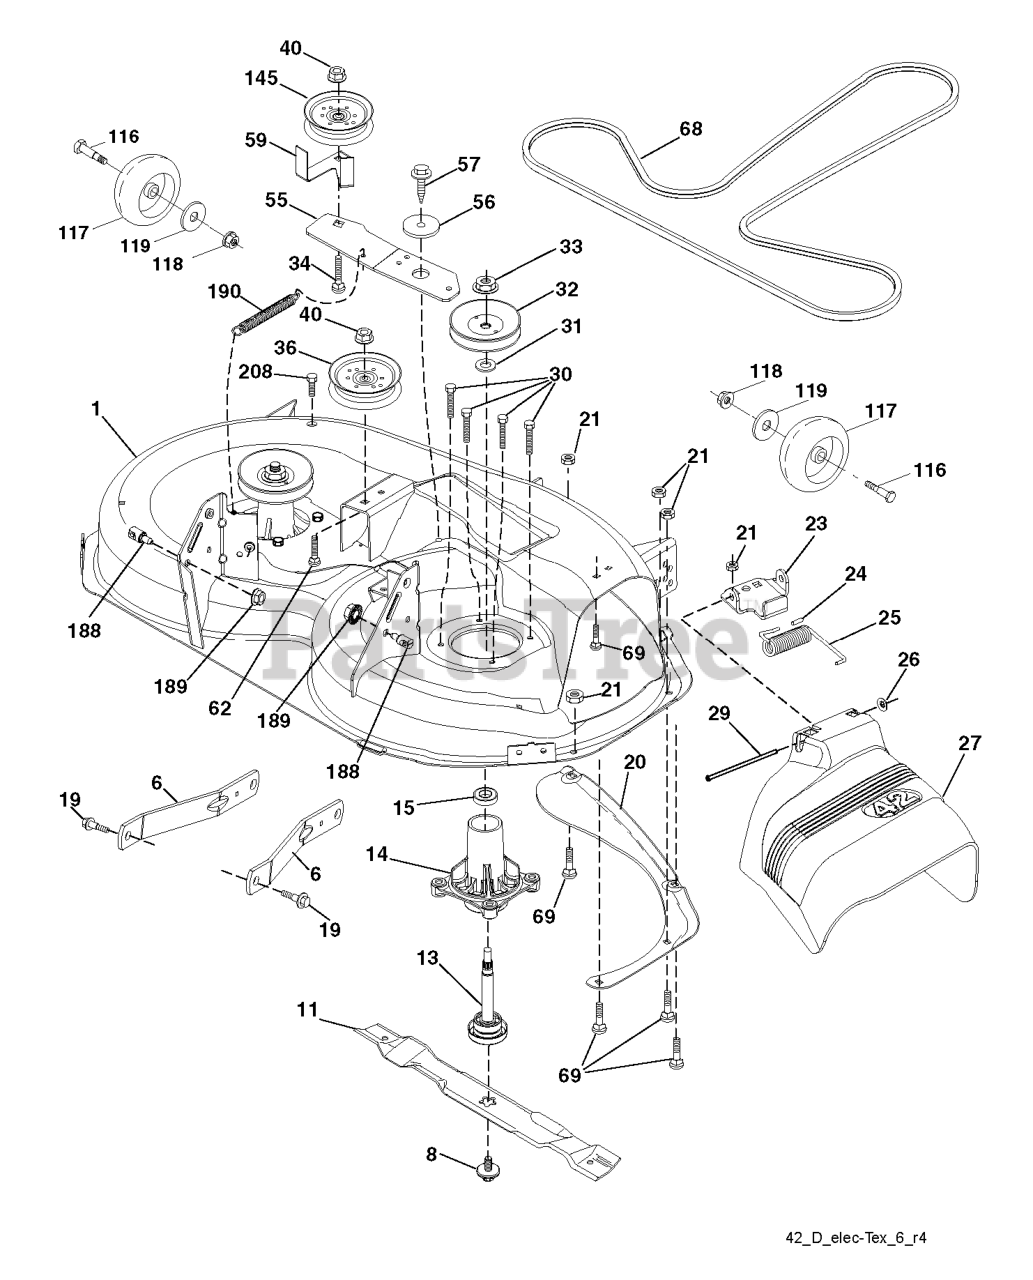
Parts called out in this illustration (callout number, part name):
1	DECK.WELDMENT.42"
6	ARM.SUSPENSION.MOWER.R
8	BOLT.WASHER.ASM.7/16-2
11	42" HI-LIFT BLADE
13	SHAFT.ASM.MDRL.N/GREASE.38
14	RP.HOUSING.MANDREL.4PT.
19	BOLT.SHOULDER
20	BAFFLE.VORTEX
21	LOCKNUT
23	BRKT.DEFLECTOR.38"2005+
24	CAP-SLEEVE LT
25	SPRING.TORSION.DEFLECT
26	NUT PUSH M
27	SHIELD.DEFLECTOR.MOWER.42"BLAC
29	ROD.HINGE
30	SCREW, WASHER HEAD
31	WASHER.SPACER.MANDREL
32	PULLEY/MANDREL
33	NUT.FLANGE.LOCK.TOP
34	BOLT.3/8-16X1.50
36	PULLEY.IDLER.2006
40	NUT LOCK FLG 3/8-16 UNC
55	IDLER.ARM.42"
56	SPACER.RETAINER
57	SCREW 3/8-16X1
59	GUARD, BELT
62	BOLT
68	BELT V SECONDARY
69	BOLT
116	BOLT M
117	WHEEL.GAGE.HALF.SPOKED
118	NUT LOCK FLG 3/8-16 UNC
119	WASHER.5/16.FLAT.STE.STD.
145	PULLEY.IDLER.48"PRIMARY
188	STUD.FASTNER.W/ANTI-ROTATE
189	NUT LOCK HEX FLANGE 5/16-18
190	SPRING.MOWER.DRIVE.ELECTRIC
208	SCREW 3/8-16X1/2
